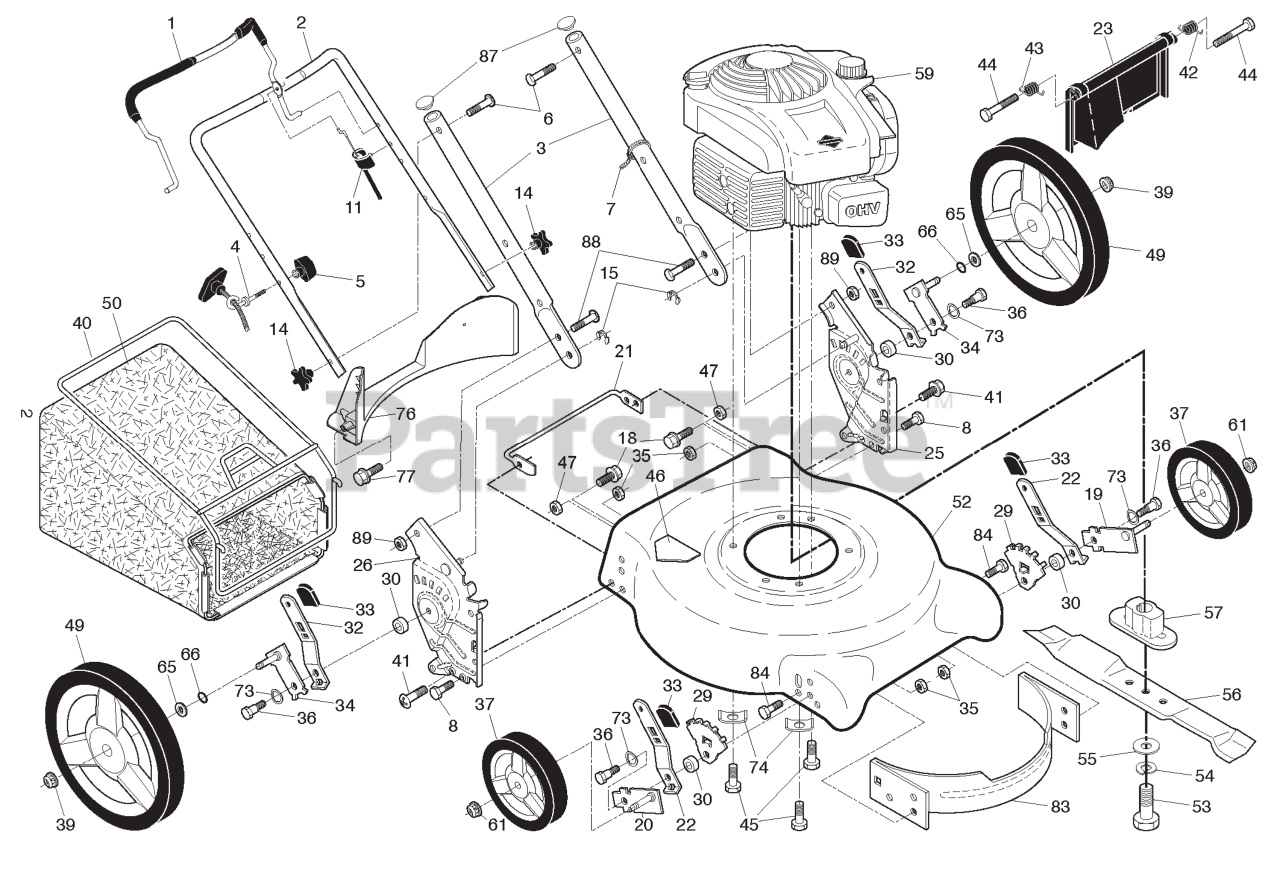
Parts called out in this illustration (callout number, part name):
1	BAIL.OM.ERGO.BENT.MZR.ORAN.668
2	HANDLE.UP.CURV.PUSH.498
4	GUIDE.ROPE.BLK.ZINC.CHROM
5	T-KNOB.NEW ROPE GUIDE
6	BOLT, HANDLE 5/16-18X1.75
7	TIE GUIDE
8	BOLT.FIN.HEX.5/16-18X3/4
11	CONTROL.ZONE.ASM
14	KNOB.HANDLE.PLASTIC.STAR.BLACK
15	HAIRPIN COTTER
18	SCREW 1/4X20
19	AXLE ARM ASSY FRONT LH
20	AXLE ARM ASSY FRONT RH
21	FOOT.GUARD.21.DOM/FGD.CE.10
22	SELECTOR SPRING, FRONT
23	DOOR.REAR.21.DOMED.498
25	BRACKET ASM.HAND.HW.21.LT.498
26	BRACKET.ASM.HAND.HW.21.RT.498
29	WHEEL ADJ BRACKET FRONT
30	SPACER.HEIGHT.ADJUSTER
32	SPRING.SEL.22.ECON.HI-WHL.RATO
33	SELECTOR KNOB
34	ARM ASM.AXLE.BZP
35	NUT.FLANGE.HEX.5/16X18.BLACK
36	SHOULDER BOLT 5/16-18
37	WHEEL AND TIRE ASSY, REAR
39	NUT.HEX.FLANGE.3/8-16.LOCKNUT
40	FRAME.BAG.21.REAR.DOMED.PUSH
41	SCREW 14-20 X 5/8
42	SPRING.LH.22.REAR.DOOR.EZ.EMPT
43	SPRING.RH.22.REAR.DOOR.EZ.
45	BOLT 3/8-16X1-1/8
46	DECAL.INTERNATIONL.CUTFINGER
49	WHEEL.11X1.75.H3SPK.RAD3.BB1
50	GBAG.24710090.GENERIC H-GRY498
52	KIT.HSG.21RD.DOME.ORG.CE
53	SCREW, HEX HD 3/8-24 X 1-3/8
54	LOCKWASHER
55	WASHER,HARDEN
56	BLADE.21.PUSH
57	ADAPTOR.BLADE.7/8
61	NUT.HEX.FLANGE.3/8-16.LO(3 2)
65	WASHER.FLAT.1/2
66	O-RING..070X.487.NEOPRENE
73	WASHER.CURVED.CYLINDRICAL
74	WASHER.ENGINE.BZP
76	BAFFLE.REAR.21DOM.REGRND.NATUR
77	SCREW.HX.13X.750
83	BAFFLE.FRONT.21.DOME.US
84	BOLT.5/16HEX.WHS.HD
87	PLUG.PLASTIC.7/8".14-20.GAUGE
88	BOLT.CARRIAGE.LN.5/16-18X.5/8
89	LOCKNUT-FLANGE 5/16-18
